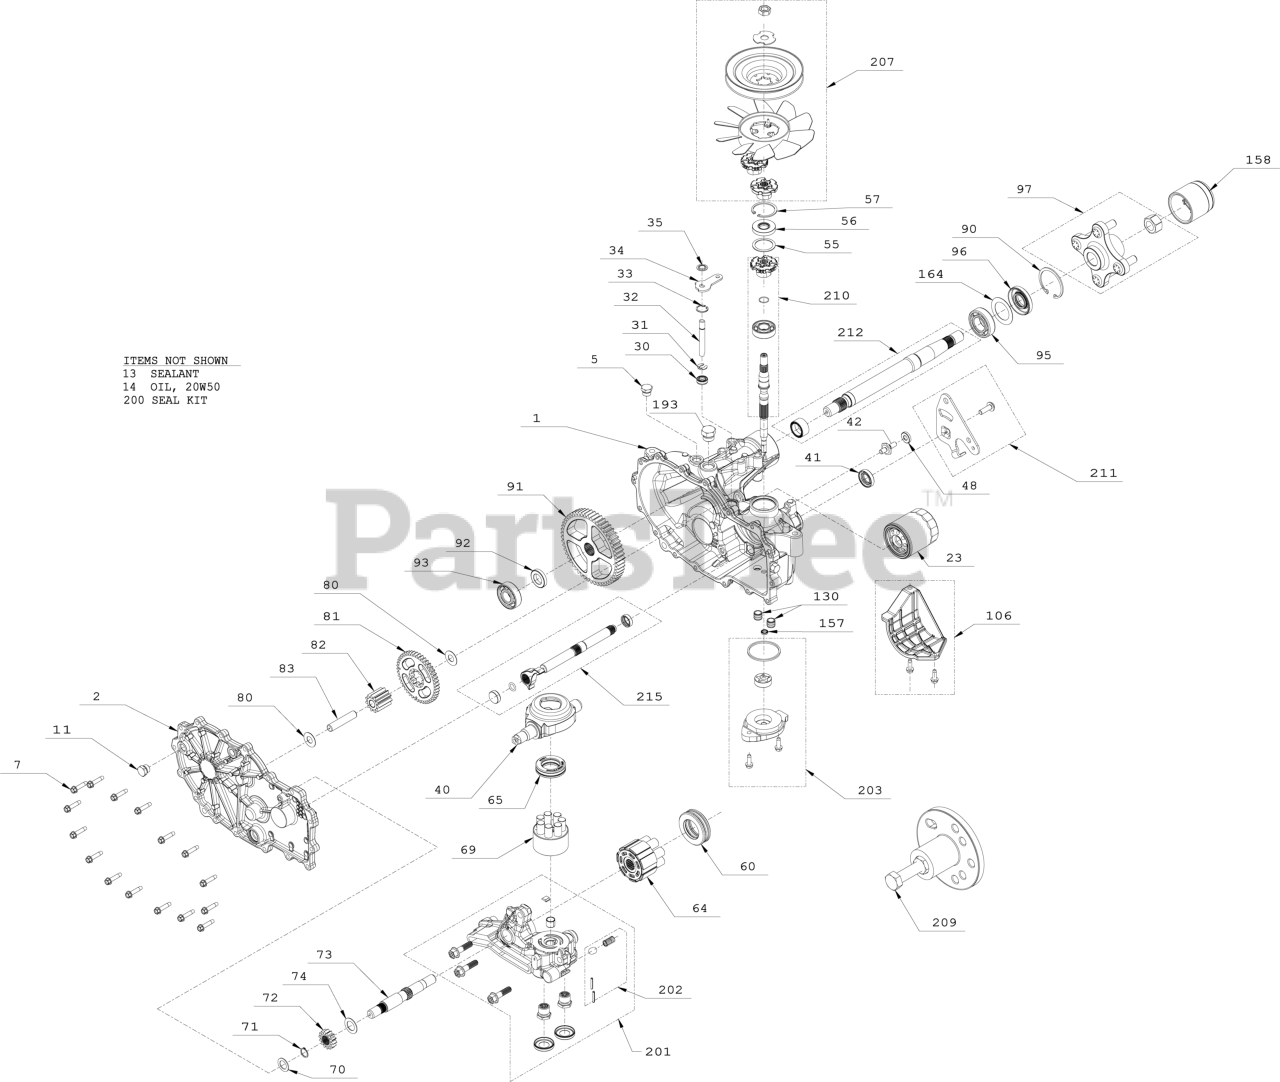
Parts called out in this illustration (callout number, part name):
1	KIT, HOUSING, MAIN, LH, CHRG, CNTL
2	KIT, SIDE COVER, LH
5	PLUG EXT HEX VENT 9/16 18
7	SCREW,HEX WASHER 1/4-20X1.125
11	PLUG EXT HEX VENT 9/16 18
13	SEALANT TUBE 10.1OZ.
14	FLUID, HYDRO 15W50 QT
14	FLUID, HYDRO 20W50 QT
23	FILTER, HYDRO-GEAR 2800 TRANS
30	Seal, lip .375 x 375 x 325
31	RING. RETAINING
32	ROD, BYPASS
33	RING, RET .750
34	ARM, BYPASS
35	RING, RTNG .
40	TRUNNION, SWASHPLATE
41	SEAL, LIP 18X32X7
42	STUD. SHORT 5/16-24
48	SPACER
55	WASHER 1.23X1.56X.04
56	SEAL, LIP 17X40X7
57	RING, RET 1.56 INT
60	HG THRUST BEARING (51462)
64	HG 16CC CYLINDER BLOCK (71579)
65	BEARING. THRUST 30 X 52 X 13
69	ASSY, BLOCK 7 PISTON
70	WASHER .63X1.0X.05
71	RING, RET 62 EXT
73	SHAFT, MOTOR
74	WASHER .71 X 1.16 X .04
80	WASHER .5X1.0X.032
81	GEAR 45 TOOTH
83	JACK SHAFT (PIN)
90	RING, RETAINING
91	GEAR 54 TOOTH
92	SPACER
93	KIT, BEARING
95	BEARING, BALL 25.4 X 52 X 15
96	SEAL, LIP
97	KIT, HUB 4 BOLT
106	KIT, FILTER GUARD
130	TUBE CHARGE TRIPLE ORING
157	KIT GEROTOR SEAL
158	CAP, AXLE
164	WASHER, 1.355 x 2.035 x .021 FLAT
201	KIT, CENTER SECTION, LH CHARGE
202	KIT CHARGE RELIEF
203	KIT, CHARGE
207	KIT, FAN / PULLEY
209	HUB PULLER 5 BLT
210	KIT INPUT SHAFT
211	KIT, CONTROL ARM
212	KIT SHAFT AXLE
215	KIT, OUTBOARD, RH ROT B / LH ROT A
